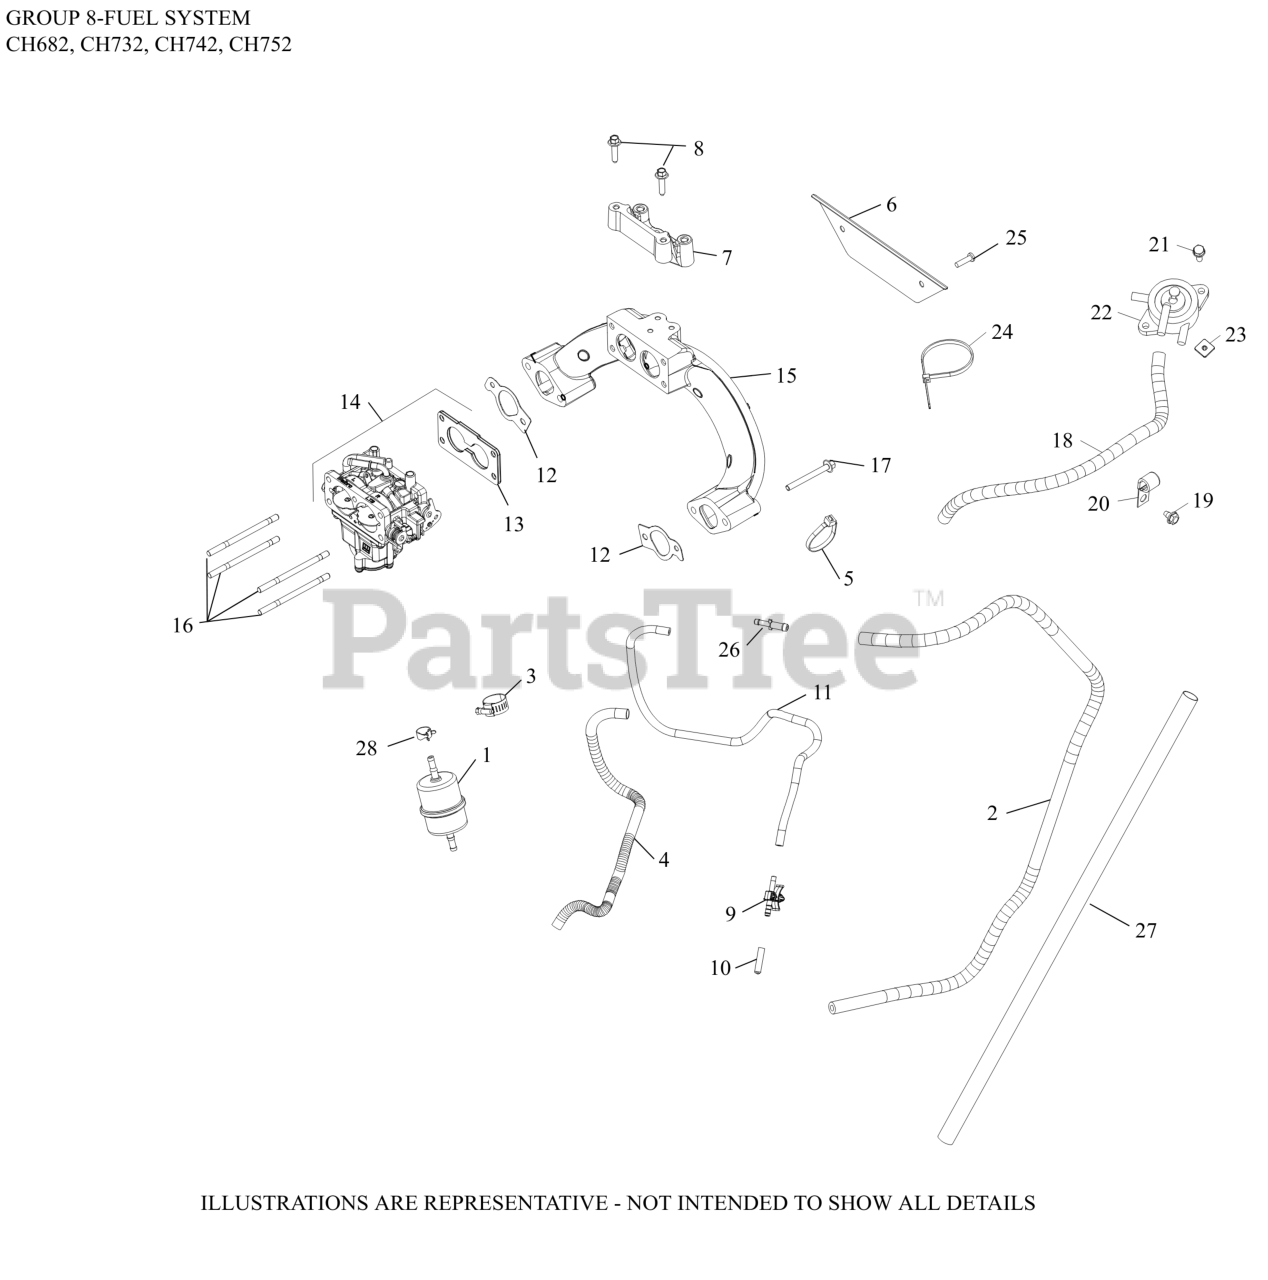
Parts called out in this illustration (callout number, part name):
1	FILTER, FUEL
2	HOSE,LW PERM.FUEL 24.00"-USE 25 111 81-S
3	CLAMP, HOSE (KM)-USE 25 237 31-S
8	SCREW, FLG M6X1.0X25
9	CONNECTOR, EVAPORATIVE
10	CAP, MASKING
12	KIT, INTAKE MANIFOLD GASKET
13	GASKET, CARBURETOR
14	CARB KIT
15	MANIFOLD, INTAK E(HORZ, 2BBL)
16	STUD,M6X1.0X96
17	SCREW, FLG M6X1.0X55
NI	KIT, HIGH ALT4000 TO 8000 FT
NI	KIT, HIGH ALTITUDE (+ 8000 FT)
NI	KIT, FUEL SHUTDOWN-USE 24 757 76-S
NI	KIT, CHOKE REPAIR-USE 24 757 77-S
NI	KIT, ACCEL PUMP REPAIR
NI	KIT, CARBURETOR REPAIR
NI	KIT, FLOAT BOWL REPLACEMENT
NI	SPRING CLAMP, HOSE
